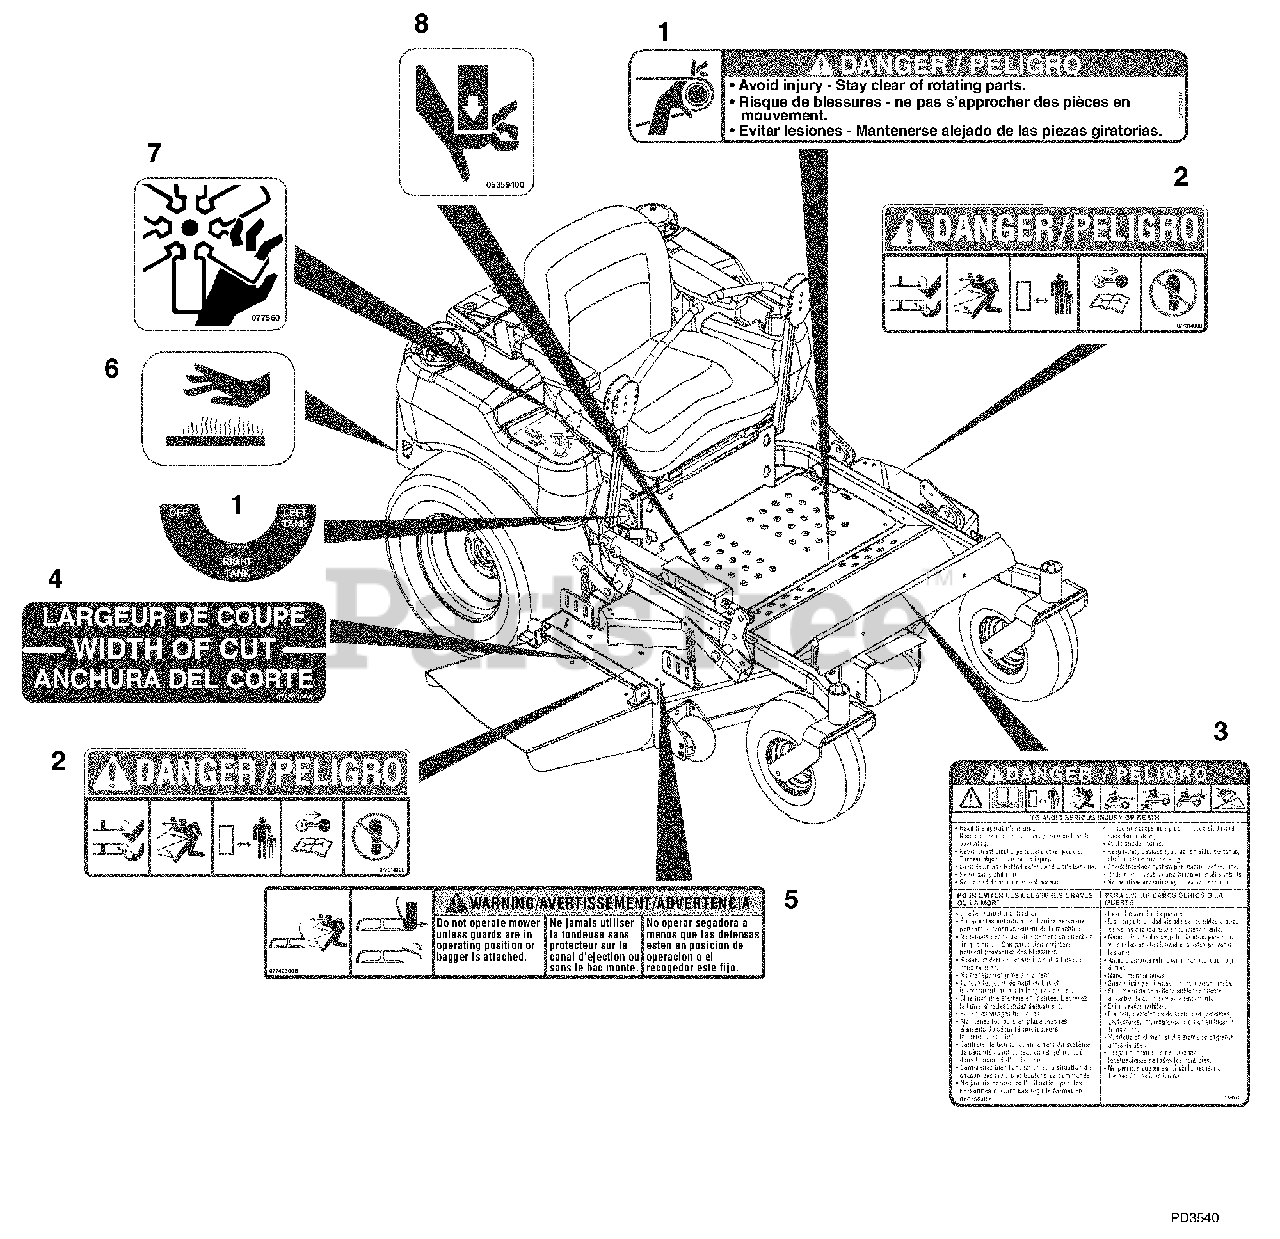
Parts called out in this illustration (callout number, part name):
1	Set, Decal-Common Danger/Fuel
2	Decal, Mower Pan Head Danger
3	Decal, Danger- Bilingual
4	Decal, Width of Cut
5	Decal, Warning
6	Decal, Hot Surface
7	Decal, Danger Fan
8	Decal, Pinch Point
